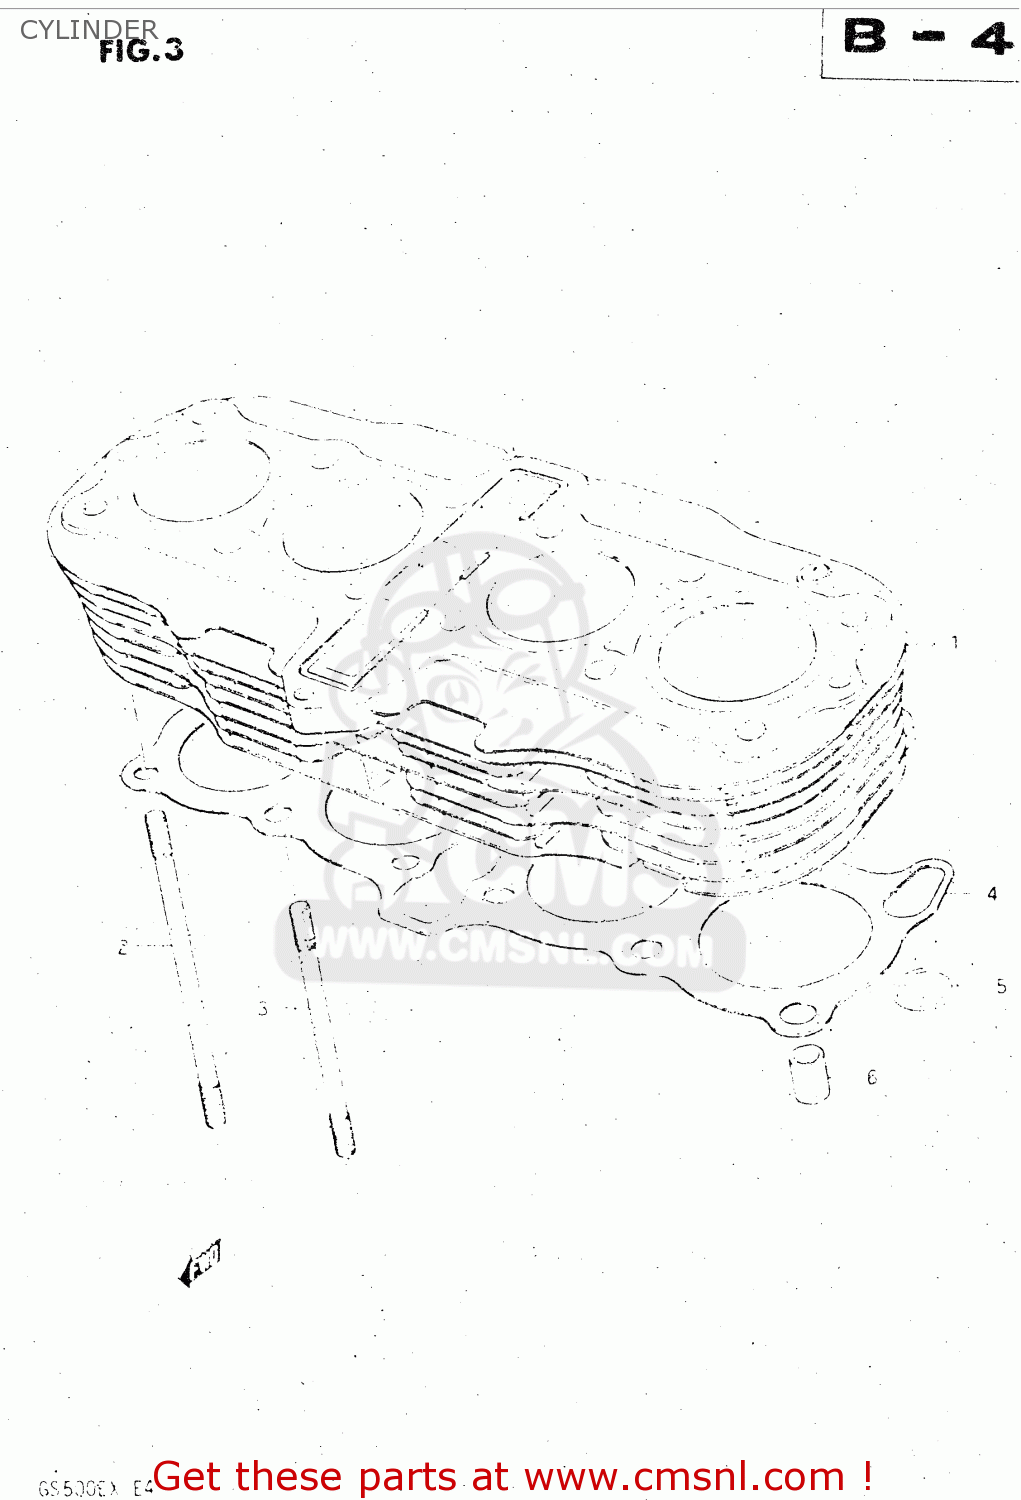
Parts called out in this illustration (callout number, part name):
1	CYLINDER
2	BOLT,STUD
3	BOLT,STUD
4	GASKET,CYLINDER (MCA)
5	INVALID PARTNUMBER
6	PIN
